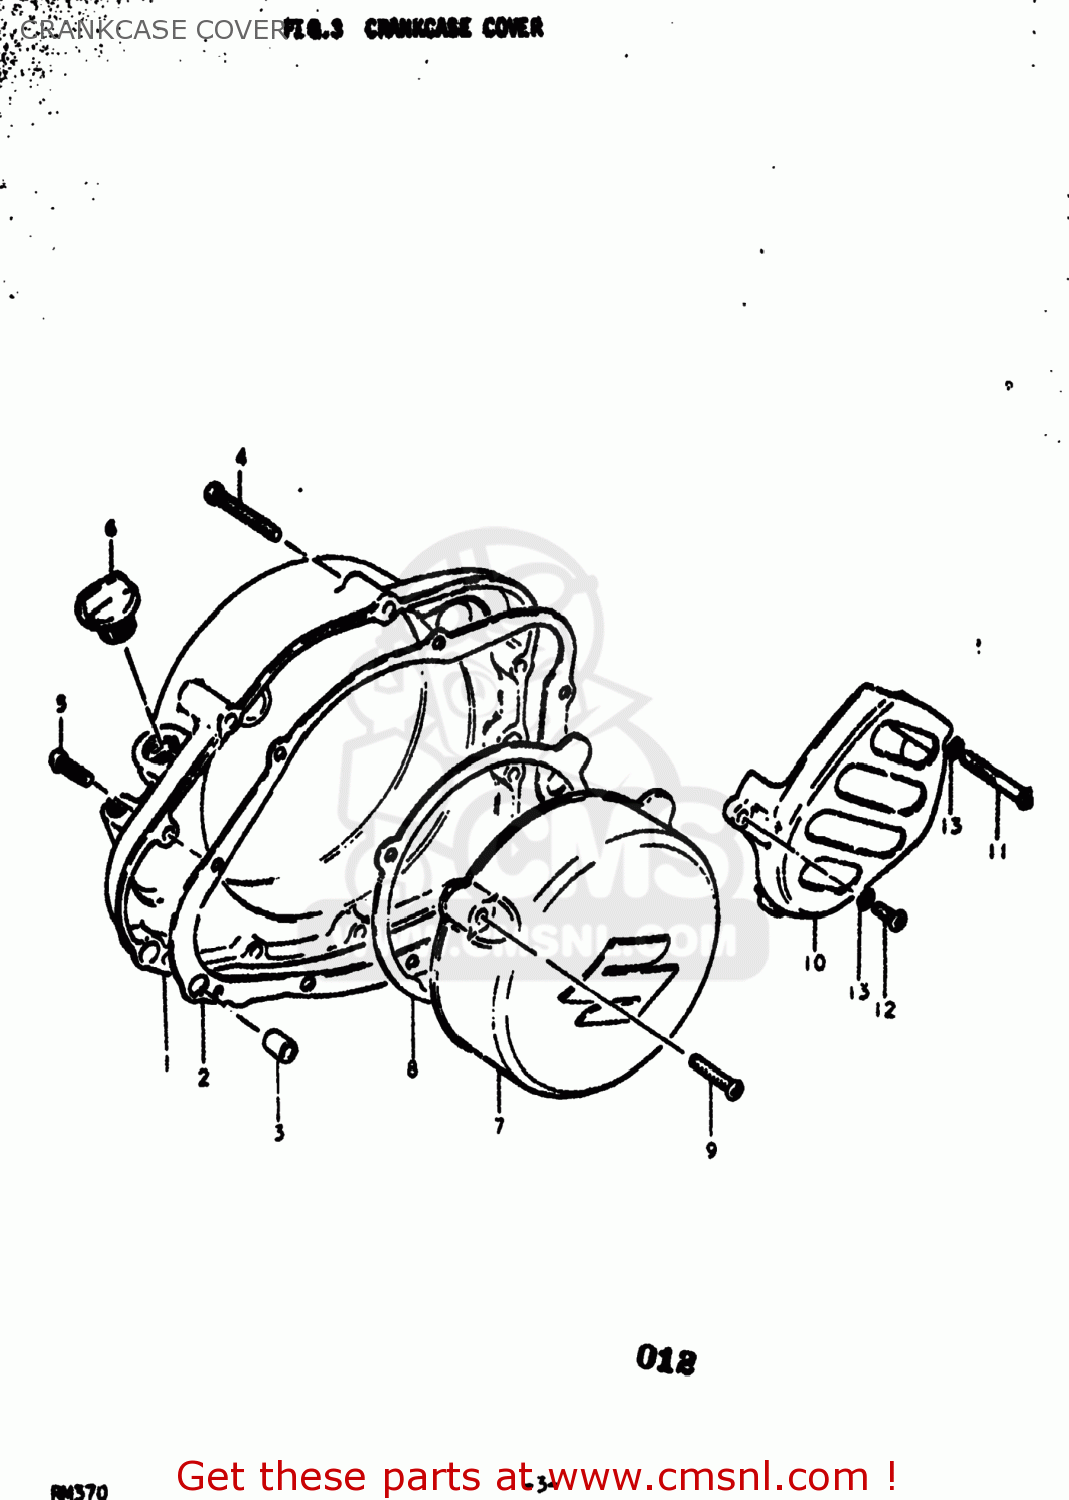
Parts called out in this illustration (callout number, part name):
1	COVER,CLUTCH
2	GASKET,CLUTCH COVER (MCA)
3	PIN
4	SCREW (6X45)
5	SCREW
6	PLUG,OIL FILTER
7	COVER,MAGNETO
8	GASKET,MAGNETO COVER (MCA)
9	SCREW
10	COVER,SPROCKET
11	SCREW
12	SCREW
13	LOCK WASHER
